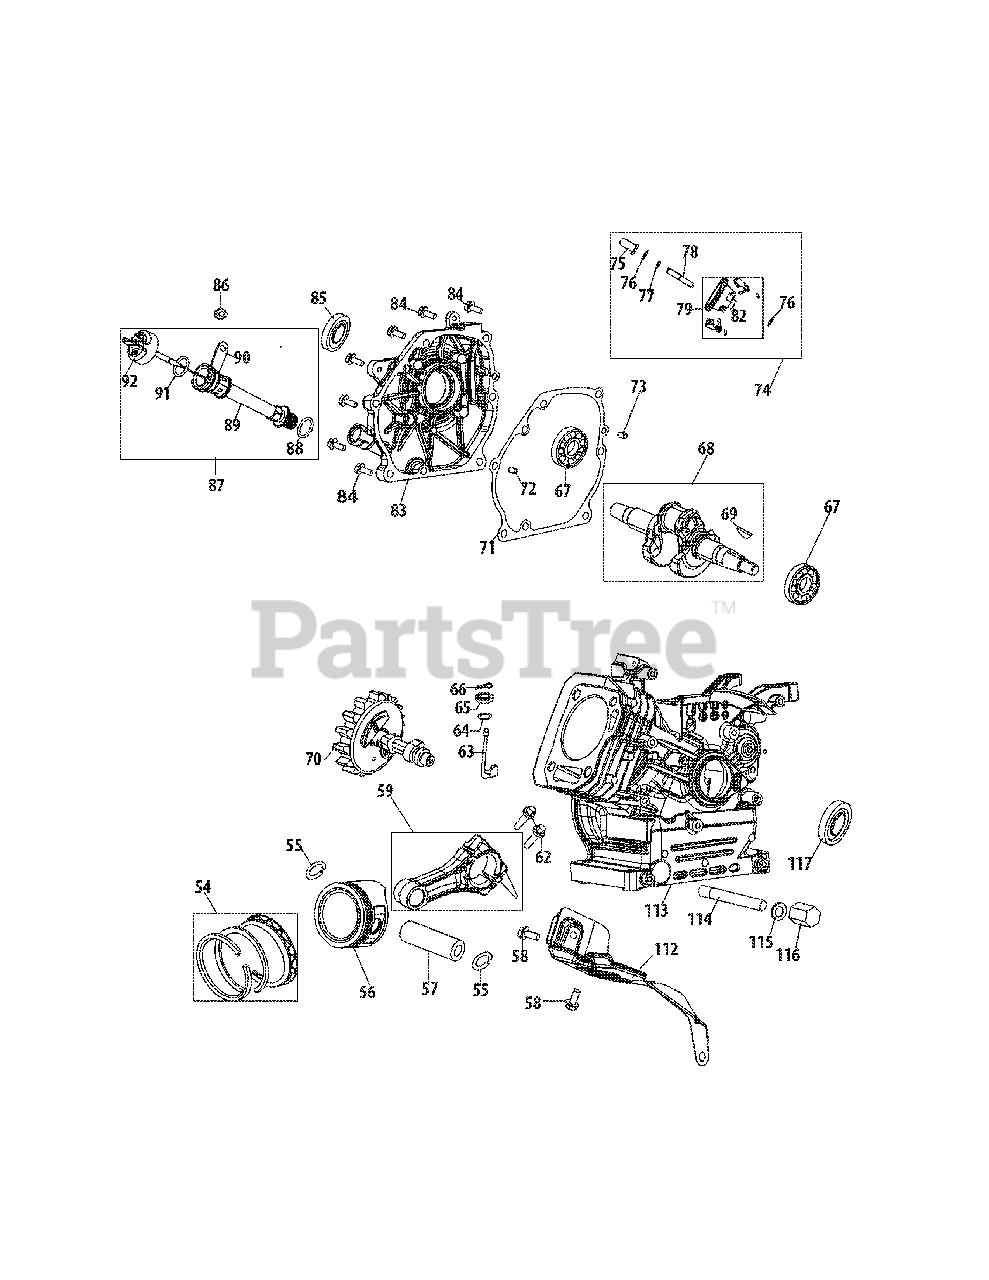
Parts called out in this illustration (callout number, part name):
54	Piston Ring Set
55	Circlip
56	Piston
57	Piston Pin
58	Bolt, M6×12
59	Connecting Rod Assembly
62	Connecting Rod Bolt
63	Governor Gear Shaft
64	O-Ring, 5.2×1.9
65	Oil Seal, 6×11×4
66	Cotter Pin
67	Bearing, 6205
68	Crankshaft
69	Woodruff Key
70	Camshaft
71	Gasket, Crankcase
72	Pin, 9×14
73	Pin, 7×14
74	Governor Gear
75	Governor Cup
76	Washer, 6.2×0.6×15
77	Retaining Ring
78	Governor Shaft
79	Governor Gear
82	Governor Gear
83	Crankcase Cover
84	Bolt, M8×32
85	Oil Seal, 25×41.25×6
86	Bolt, M6×16
87	Dipstick
88	O-Ring, 15.5×1.5
89	Dipstick Seat
91	O-Ring, 21×2.77
92	Dipstick
112	Shroud
113	Crankcase
114	Oil Drain Pipe
115	Washer, 10×1.5×16
116	Drain Bolt
117	Oil Seal, 25×41.25×6
